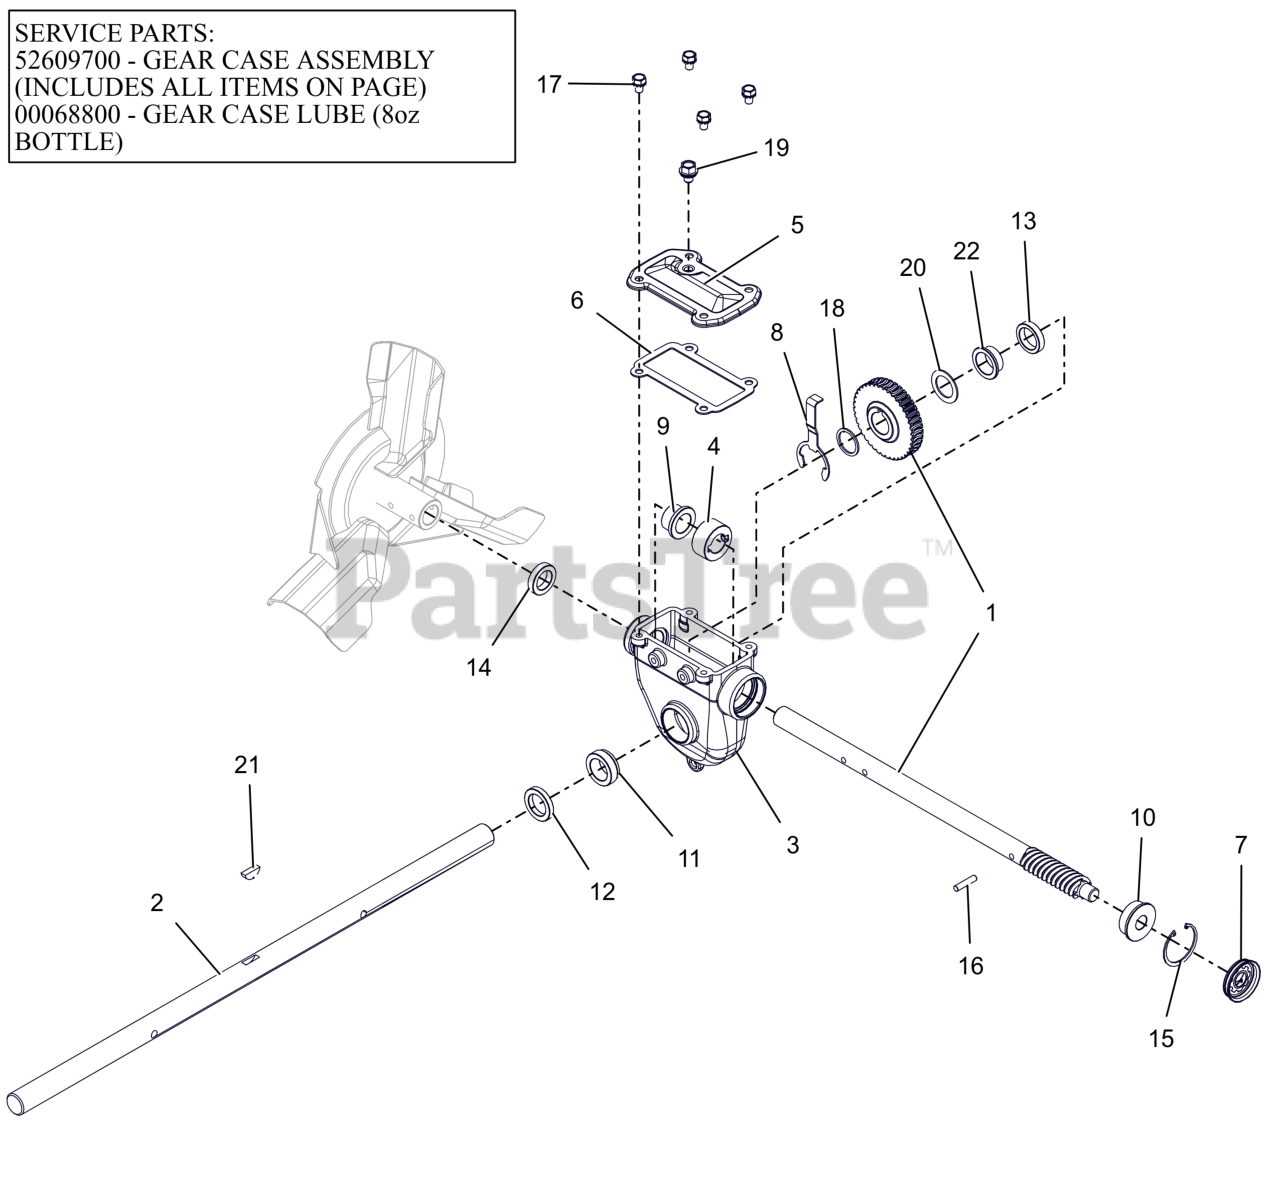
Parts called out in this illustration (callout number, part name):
1	ASSY, WORM SHAFT & GEAR
2	SHAFT, RAKE-28"
3	GEARCASE, LARGE MACHINED
3	GEAR CASE, 28" IRON PRO TOP-LD
3	ARIENS L3 LUBE, 8 OZ BOTTLE
4	THRUST COLLAR, .875"ID SLIPFIT
5	COVER, TOP - LARGE IRON
6	GASKET, TOP - LARGE GEARCASE
7	COVER, GEAR CASE 1.75"
8	BUSHING RETAINER, LARGE
9	BSHG-FLG .879X1.128X.75X1.45
10	BSHG-FLG .628X1.503X.58X1.725
11	BSHG-FLG LARGE, RIGHT
12	SEAL-OIL .999X1.500X.250 TBC29
13	SEAL-OIL .999X1.375X.312 TBC29
14	SEAL-OIL .873X1.375X.312 TBC29
15	RG-RTNG-INT 1.750X.062
16	PIN-STR .250X1.12 6150
17	BLT, SEMS .31-18X.50 G5 ZCC
18	WSHR, FLT 1.010X1.250X.068 ZCC
19	SCR, .380-15X.500 W/SEAL WASHER
20	WSHR, FLT 1.010X1.505X.062 ZCC
21	KEY-WDRF .25X.875 HRD #A
22	BSHG-FLG 1.006X1.128X.555X1.45
